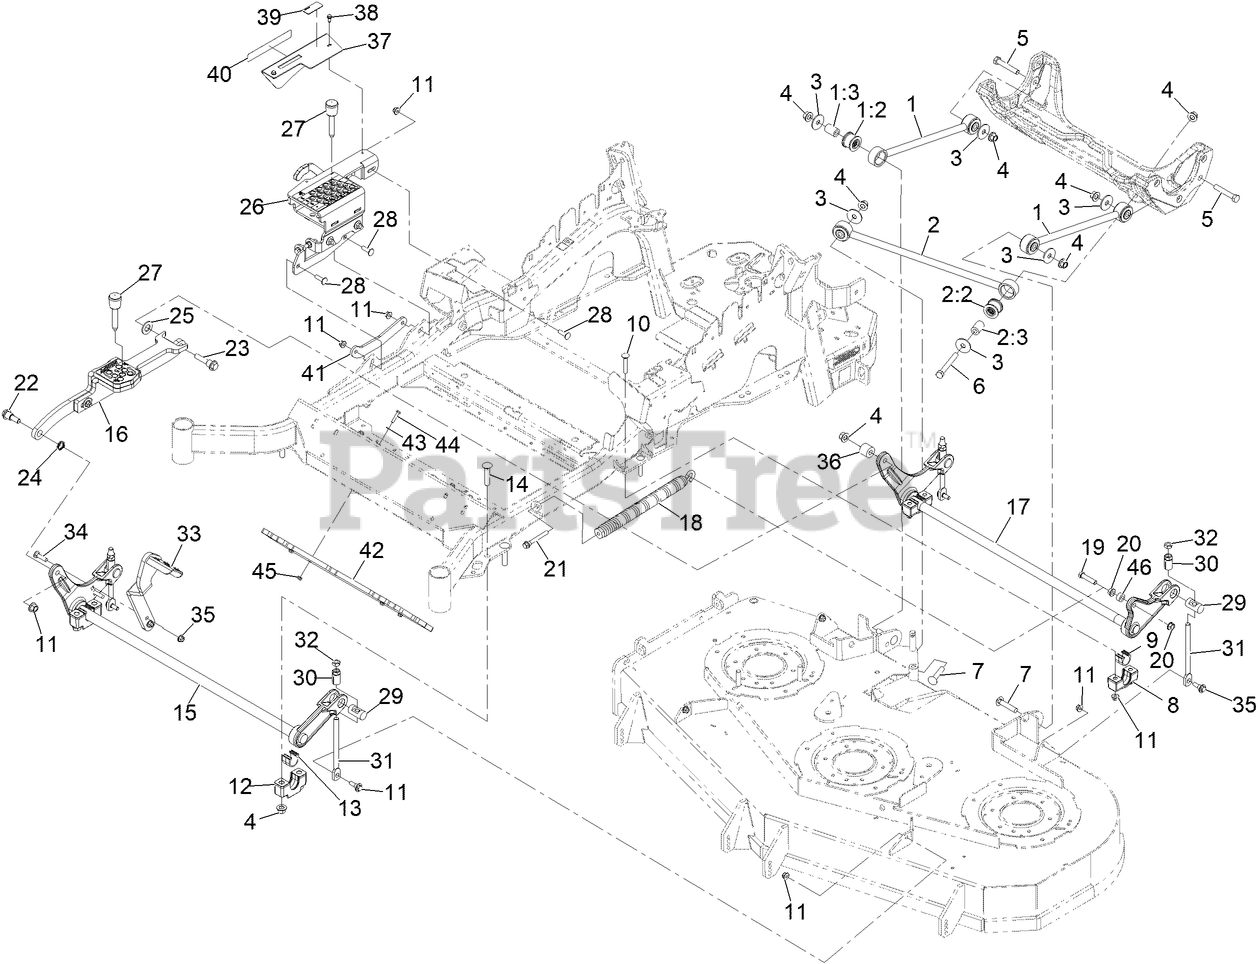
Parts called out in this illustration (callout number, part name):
1	DECK STRUT ASM
1:2	BUSHING-SUSPENSION, RUBBER
2	PANHARD ROD ASM
2:2	BUSHING-SUSPENSION, RUBBER
3	WASHER-THRUST
4	Nut-Lock 1/2-13
5	SCREW-HH
6	SCREW-HH
7	SCREW-CARR
8	SUPPORT-CROSS SHAFT, BEARING REAR
9	BEARING-CROSS SHAFT, REAR
10	Bolt-Carriage 3/8-16 X 2 1/4
11	NUT-HF, NI
12	SUPPORT-CROSS SHAFT, BEARING
13	BEARING-CROSS SHAFT, FRON
14	Bolt-Carriage 1/2-13 X 2 1/2 Spl Neck
15	Shaft- Deck Lift Front [black]
16	ASM- Link Deck Lift
17	Shaft- Deck Lift Rear [black]
18	SPRING-EXTENSION
19	SCREW-HH
21	BOLT-SHOULDER
22	SCREW-SHOULDER, HHF 1/2-13 X 1.12
23	SCREW-HHF, SHOULDER
24	WASHER-WAVE
25	WASHER-FLAT
26	ASM- Box HOC
27	ASM- HOC PIN
28	Bolt-Carriage 3/8-16 X 1 1/4
29	TRUNNION
30	ADJUSTER-LIFT, DECK
31	LINK-ADJUSTER, DECK LIFT
32	NUT-JAM
33	LEVER-FOOT
34	SCREW-CARR
35	SCREW-SHOULDER, HHF
36	Bushing- Link
37	ASM- Cover W/Decal
38	SCREW-HWH
39	Decal-Lever Lock, CE
40	DECAL-X-SERIES
41	Plate- Support
42	Weight-Toe Board
43	WASHER-FLAT
44	SCREW-HH
